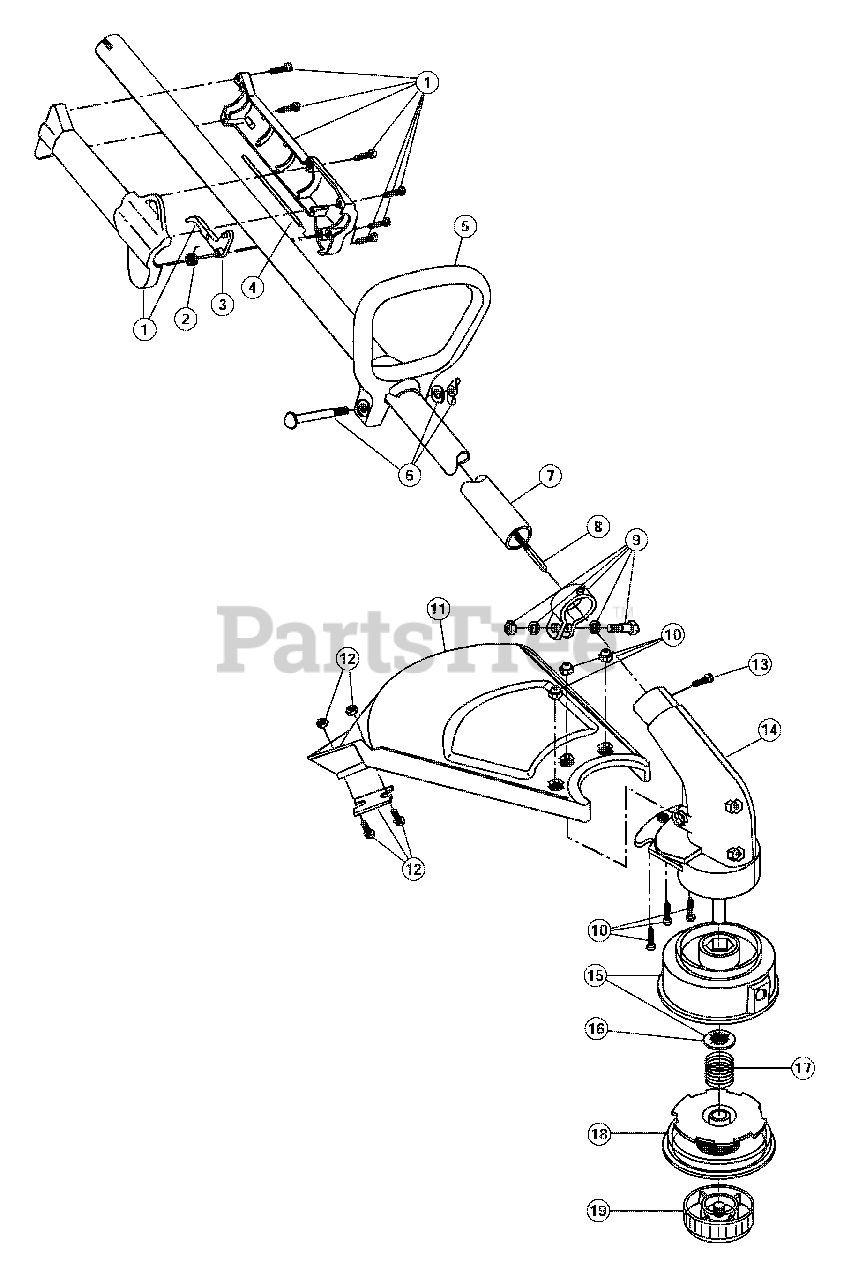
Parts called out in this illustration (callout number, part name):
1	Throttle Housing and Trigger Assembly
2	Throttle Trigger Spring
3	Throttle Trigger
4	Throttle Cable Housing Assembly
5	D-Handle
6	D-Handle Hardware Assembly
7	Drive Shaft Housing Assembly
8	Flexible Drive Shaft
9	Lower Clamp Assembly
10	Guard Mounting Screw Assembly
11	Guard and Blade Assembly
12	Blade Assembly
13	Anti-Rotation Screw
14	Gearbox Assembly
15	Outer Spool Assembly
16	Retainer
18	Inner Reel
19	Bump Head Knob Assembly
